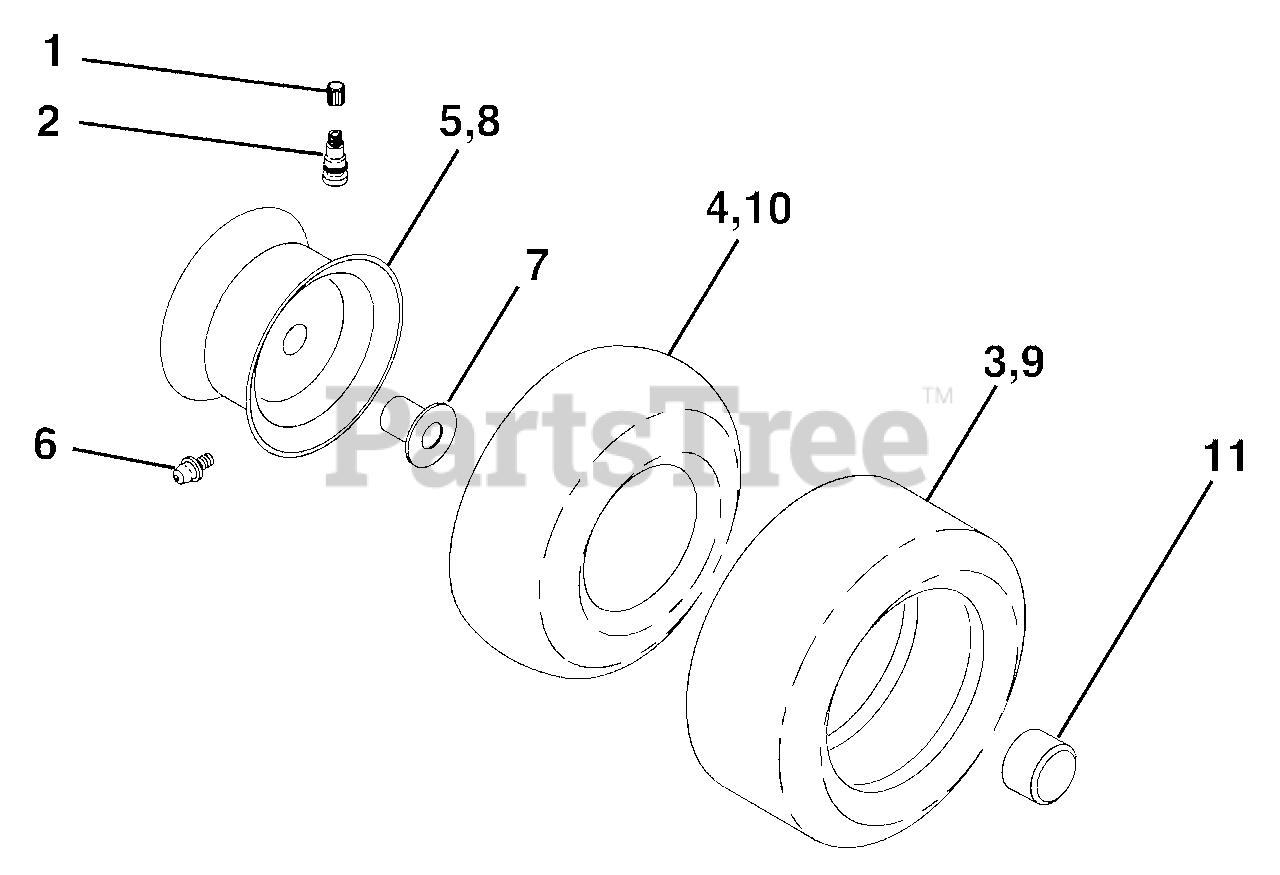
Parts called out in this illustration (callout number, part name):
1	Cap Valve Tire
2	Stem Valve
3	Tire F T 15 x 6 0 - 6
4	Tube Front
5	Rim Asm 6" front
6	Fitting Grease
7	Bearing Flange
8	Rim Asm 8" rear
9	Tire R T 20 x 10-8
10	Tube Rear
11	Cap Axle Blk 1 50 x 1 00
